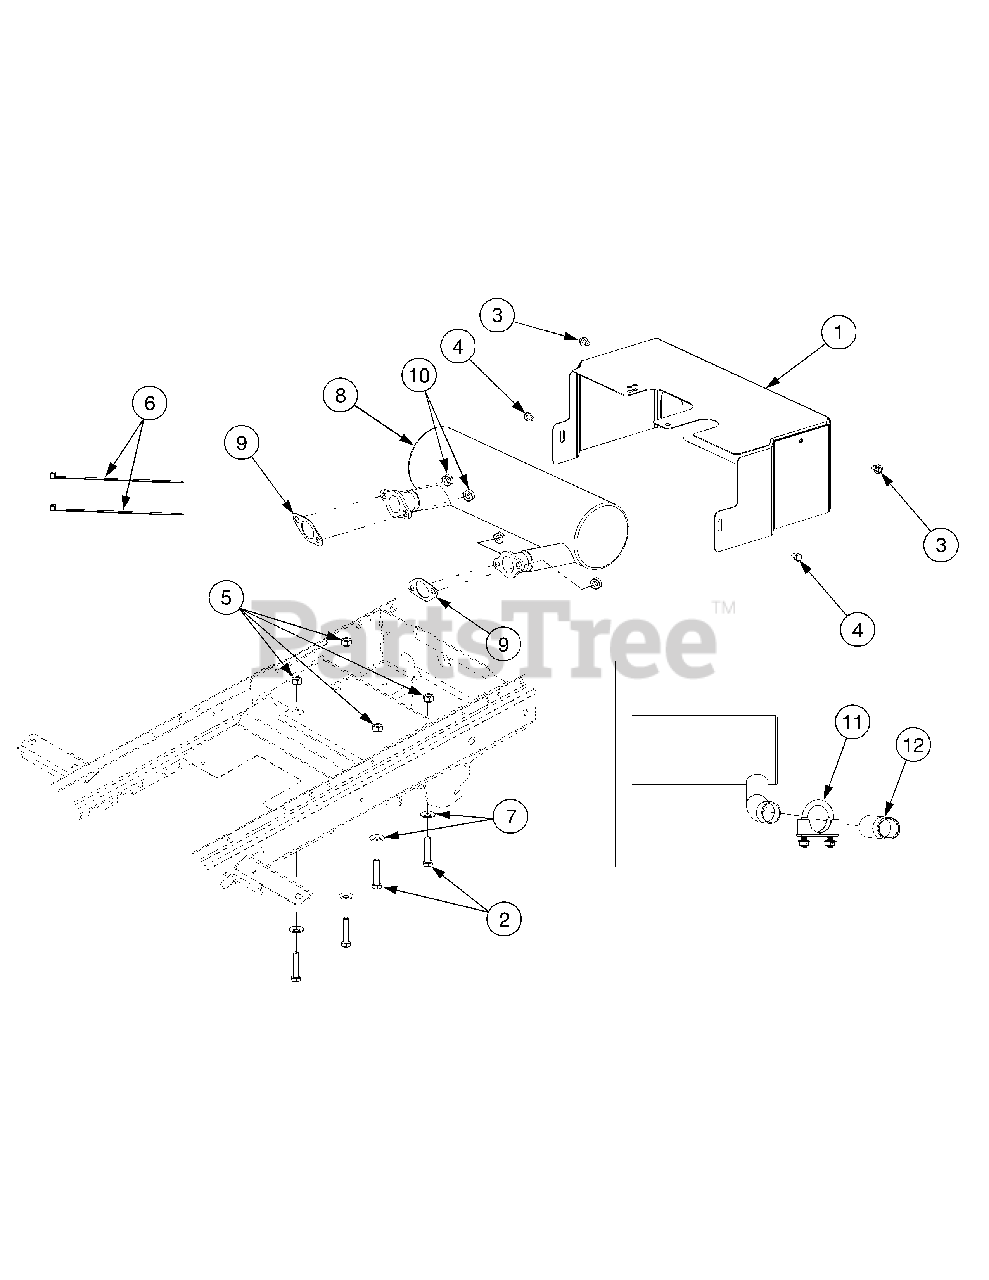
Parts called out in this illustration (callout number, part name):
1	Shield, Heat
1	Muffler Extension Shield
1	Pop Rivets 3/16" x .450"
1	Flat Washer .194" x .62" x .063"
2	Bolt, Eng Mount, 3/8-24 x 1.75 GR5
3	Screw, Hx Wsh Hd Tapp, 1/4-20 x .375
4	Screw, Hex Cap, M6 x 1 x 10
5	Nut, Hex Lock, 3/8-24
6	Tie, Cable
7	Washer, Bell, .380 x .88 x .062
8	Muffler Assembly
9	Gasket, Exhaust
10	Nut, Hex Flange
11	Clamp, Muffler
12	Pipe Extension, Exhaust
